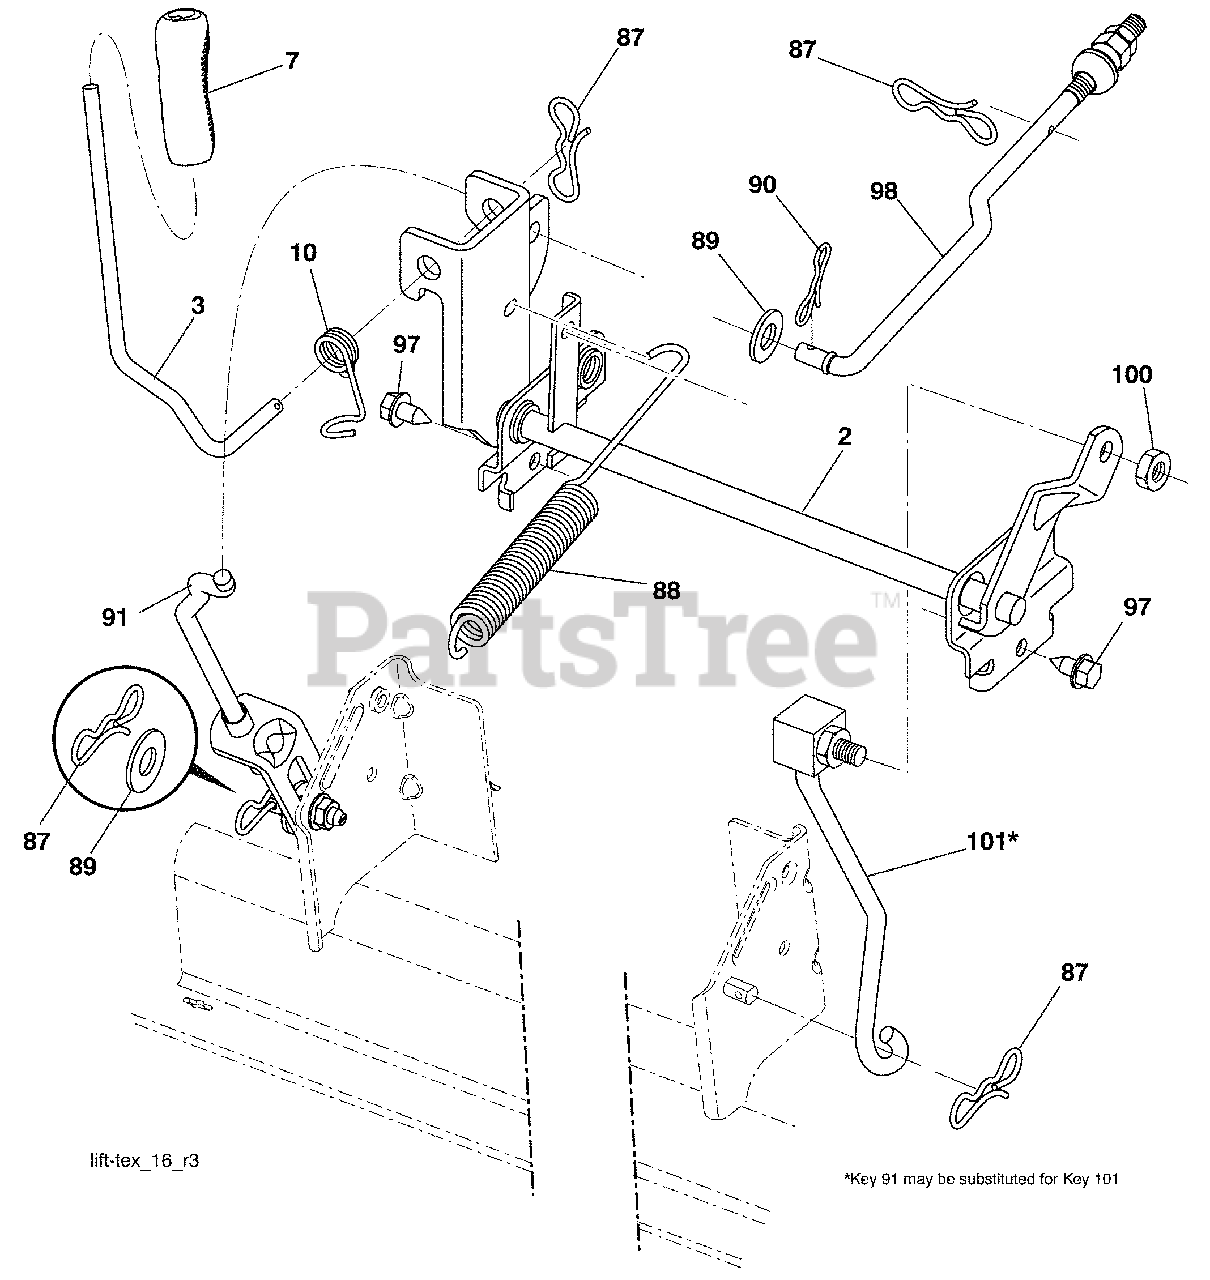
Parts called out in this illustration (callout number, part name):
2	Shaft Asm., Lift
3	Lever Asm., Lift RH
7	Grip, Lever
10	Spring Torsion
87	Pin Cotter 7/16 Bow Tie Lock
88	Spring Lift Assist
89	Washer Clear Zinc
90	Pin Cotter 5/16 Bow Tie Lock
91	Link Lift Susp Mower Rear
97	Screw 3/8-16 x 3/4
98	Link Lift Susp. Front Mower
100	Nut Center Lock 3/8-16 unc
101	Link Asm. Lift FXD
